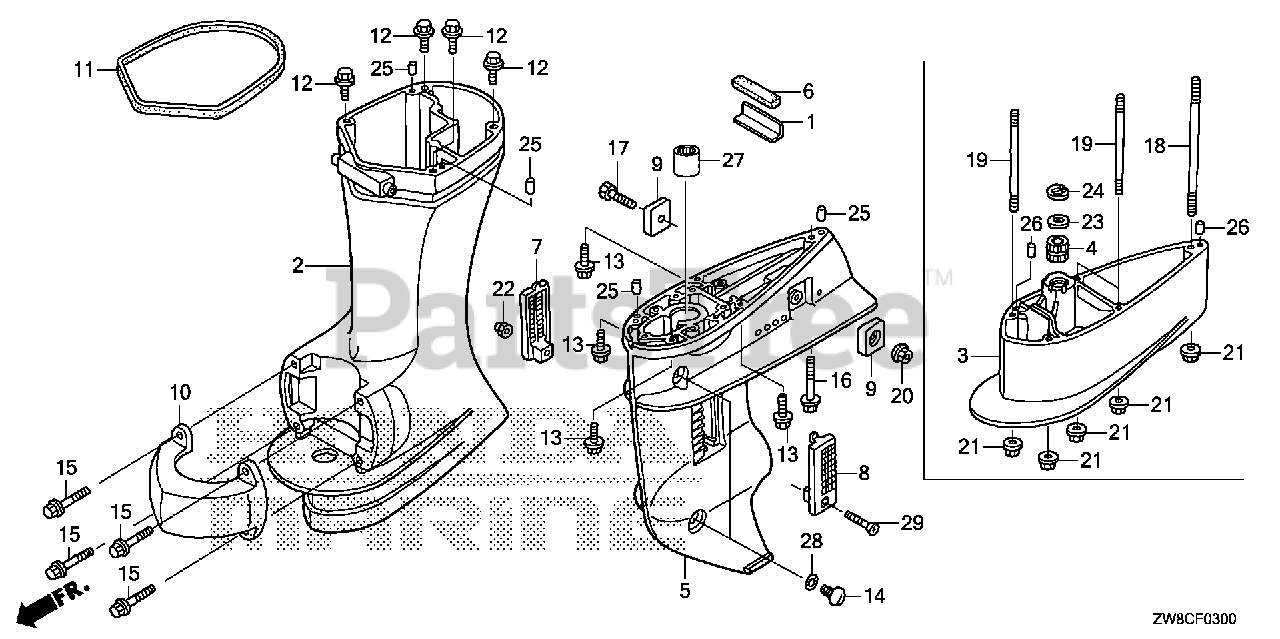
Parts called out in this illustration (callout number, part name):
1	PLATE, RUBBER SETTING
2	CASE, EXTENSION *NHB14M* (L) (AQUA MARINE SILVER METALLIC)
5	CASE, GEAR *NHB14M* (AQUA MARINE SILVER METALLIC)
6	GROMMET, GEAR CASE
7	SCREEN, R WATER
8	SCREEN, L. WATER
9	METAL, ANODE
10	HOUSING, MOUNTING (LOWER) *NHB14M* (AQUA MARINE SILVER METALLIC)
11	RUBBER, COVER (LOWER)
12	BOLT, FLANGE (8X35) Use from Frame SN 4800713.
13	BOLT, FLANGE (6X23) Use from Frame SN 4800343.
14	BOLT, OIL CHECK
15	BOLT, FLANGE (6X20) (ENGINE NO.)
16	BOLT, FLANGE (6X75)
17	BOLT, HEX. (6X25) Use up to Frame SN 4800342.
20	NUT, SELF-LOCK (6MM)
22	NUT, SELF-LOCK (5MM)
25	PIN, DOWEL (6X10)
27	BUSH, PINION GEAR
28	O-RING (6.9X1.45)
29	SCREW, OVAL (5X28)
